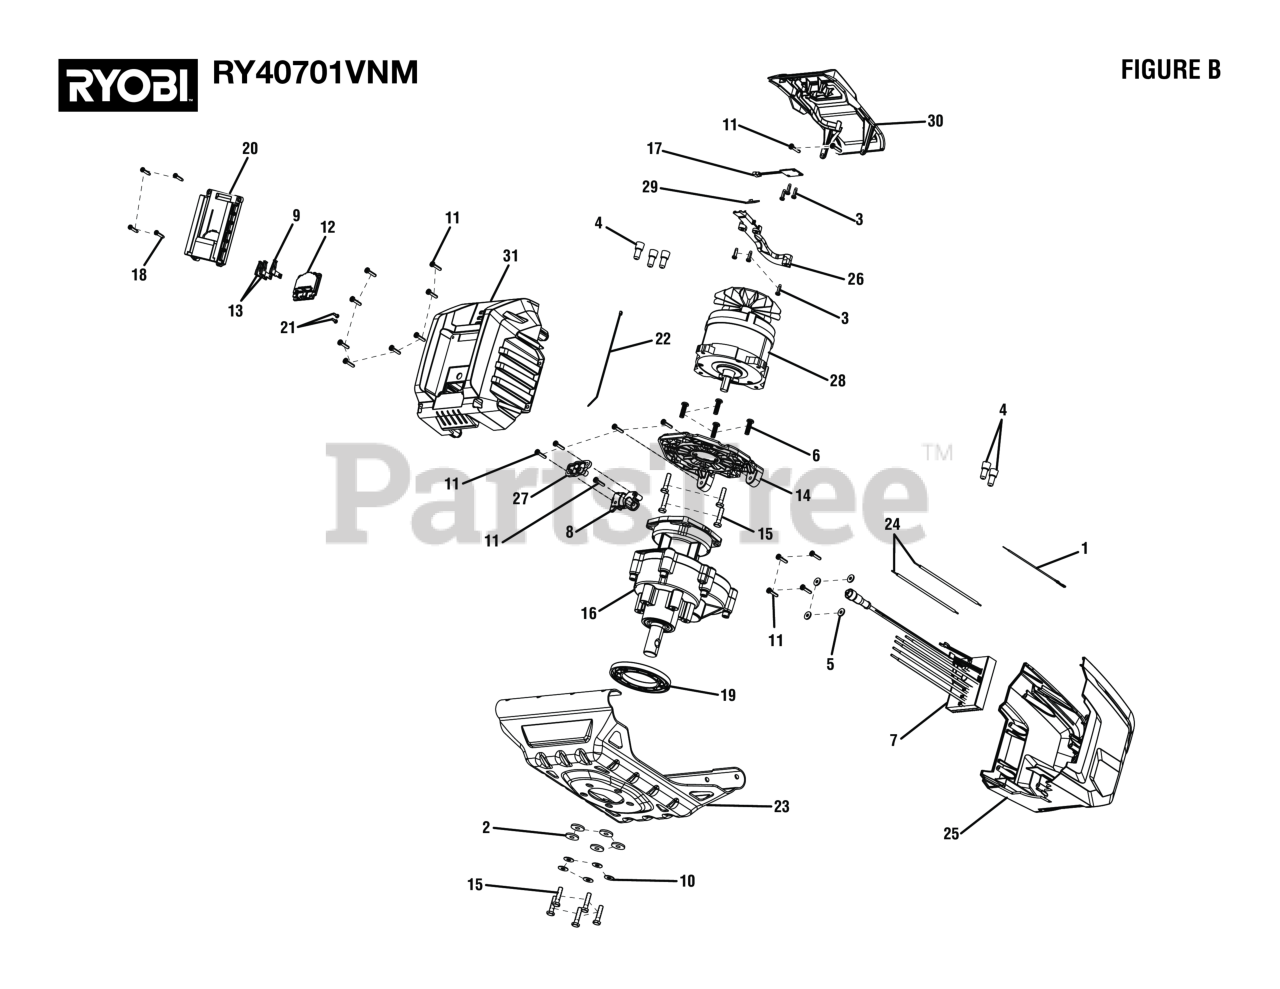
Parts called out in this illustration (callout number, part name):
1	Wire Assembly
2	Isolation Bushing
3	Screw (M4 x 14 mm, T15 Torx Pan Hd.))
4	Close-End Connector
5	Washer (ID 4.3 x OD12 x 1.5t)
6	Screw (M6 x 20 mm, T27 Torx Button Hd.)
7	Motor Controller
8	Cable Strain Relief Base
9	Battery Connection Terminal
10	Washer (ID6.2 x OD15 x 0.08t)
11	Screw (M4 x 18 mm, T20 Torx Pan Hd. S.T.)
12	Common Foot Cover
13	Battery Connection Terminal
14	Motor Mounting Bracket
15	Bolt (M6 x 26 mm, Hex Hd.)
17	Gyro Circuit Board Assembly
18	Screw (M4 x 16 mm, T20 Torx Socket Pan Hd.)
19	Isolation Ring
20	Battery Foot Adapter
21	Screw (M3 x 8 mm, Pan Hd., Pan Hd)
22	Cable Tie
23	Base Plate
24	Wire Assembly
25	Front Housing
26	Wire Retainer
27	Cable Strain Relief Top
29	Circuit Board LED
30	Top Housing
31	Rear Housing
